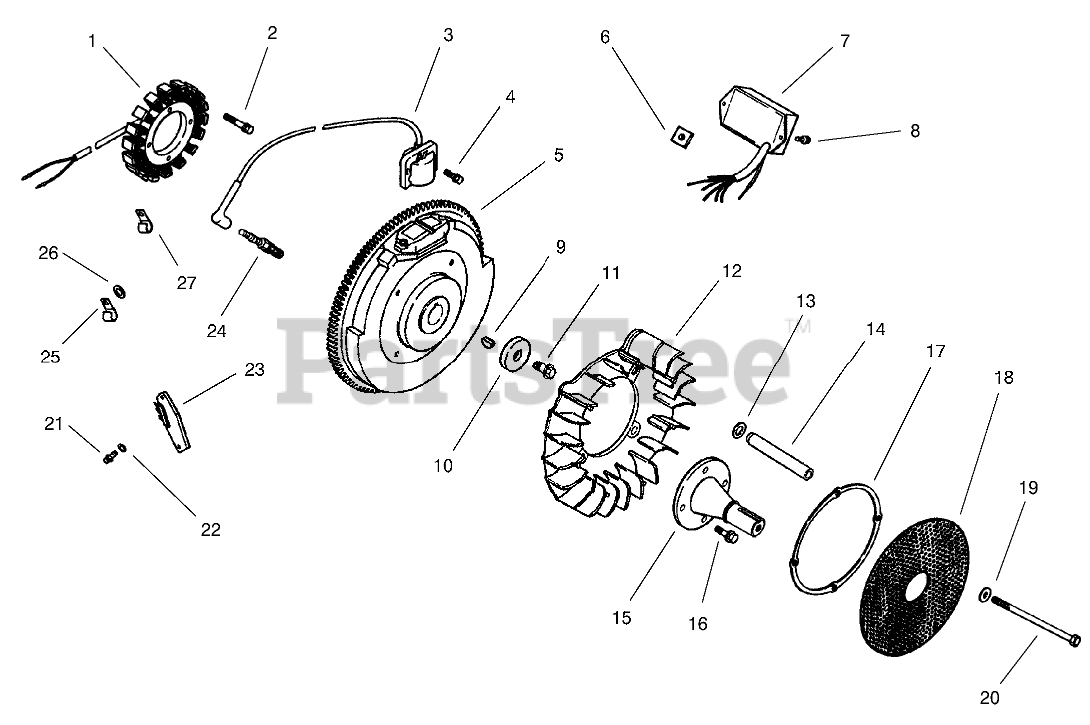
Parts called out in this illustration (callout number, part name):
1	Kit, 15 amp stator (Incl. 24 126 71 bracket)
2	Screw
3	Module-Ignition
4	Screw-HSH
5	Flywheel
6	Nut-Plastic
7	Module, speed adv.
8	Screw
9	Key
10	Washer
11	Screw
12	Fan
13	Washer, sping
14	Spacer
15	Shaft, front drive
16	Screw
17	Ring-Support
18	Screen-Grass
19	Washer
20	Screw-Hex
21	Screw
22	Washer
23	Rectifier-Regulator
24	Plug-Spark
25	Clamp
26	Washer
27	Clip
